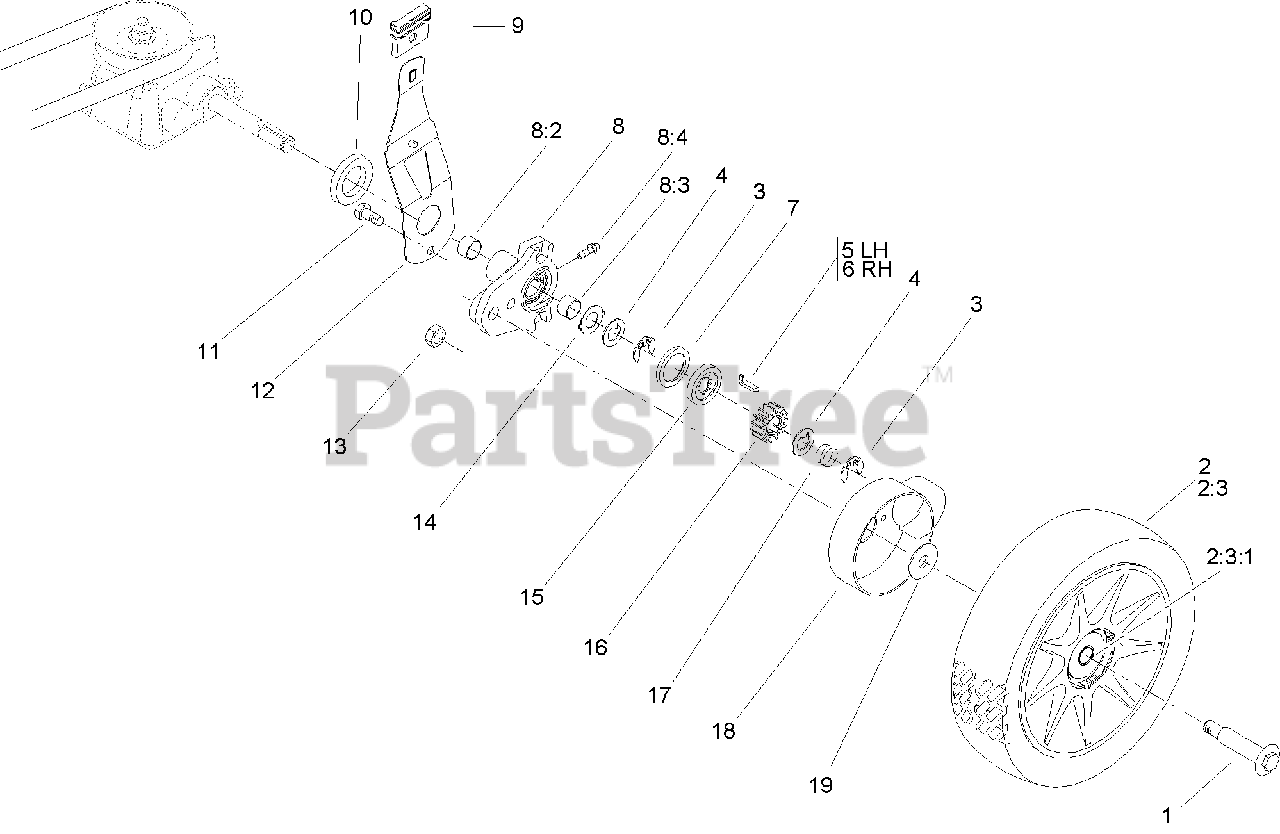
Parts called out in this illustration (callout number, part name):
1	BOLT-SHOULDER
2	WHEEL AND TIRE ASM
2:3	Wheel ASM
3	KLIPRING-LOCKING
4	WASHER-THRUST, KEYED
5	KEY-ROCKING, LH
6	KEY-ROCKING, RH
7	RING-FRICTION
8	REAR HEIGHT ADJUSTMENT ARM ASM
8:4	FITTING-GREASE
9	KNOB-LEVER, HEIGHT ADJUSTMENT
10	SPACER-AXLE SHAFT
11	SCREW-HWH
12	REAR SPRING ARM ASM
14	WASHER-ARM, PIVOT
15	WASHER-CLUTCH
16	GEAR-PINION
17	SPRING-COMPRESSION
18	COVER-WHEEL
19	WASHER-STEPPED
